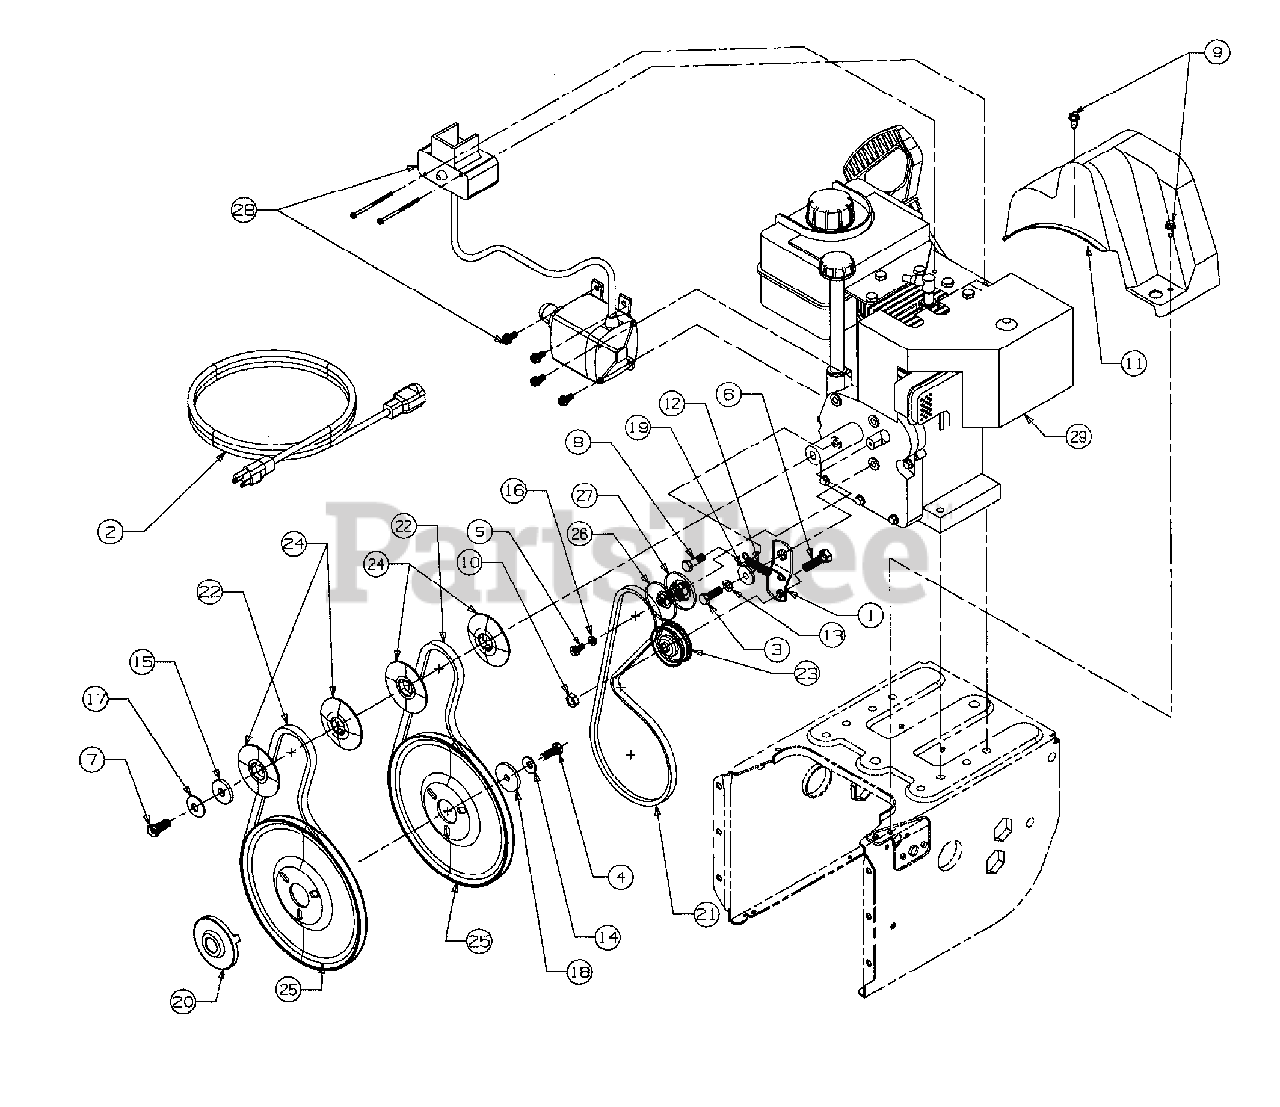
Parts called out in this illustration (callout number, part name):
3	Screw - Hex
4	Screw - Hex
5	Screw - Hex
6	Screw - Hex
7	Screw - Hex
8	Screw - Hex
9	Screw - Hex
10	Nut - Hex
11	Cover - Belt
12	Spring
13	Washer - Lock
14	Washer - Bell
15	Washer - Flat
16	Washer - Lock
17	Washer - Bell
18	Washer - Flat
19	Spacer
20	Adapter - Pulley
21	V-Belt
22	V-Belt
23	Idler - Flat
24	Pulley Half
25	Pulley - Auger
26	Pulley Half
27	Pulley Half
28	Electric Start Kit
